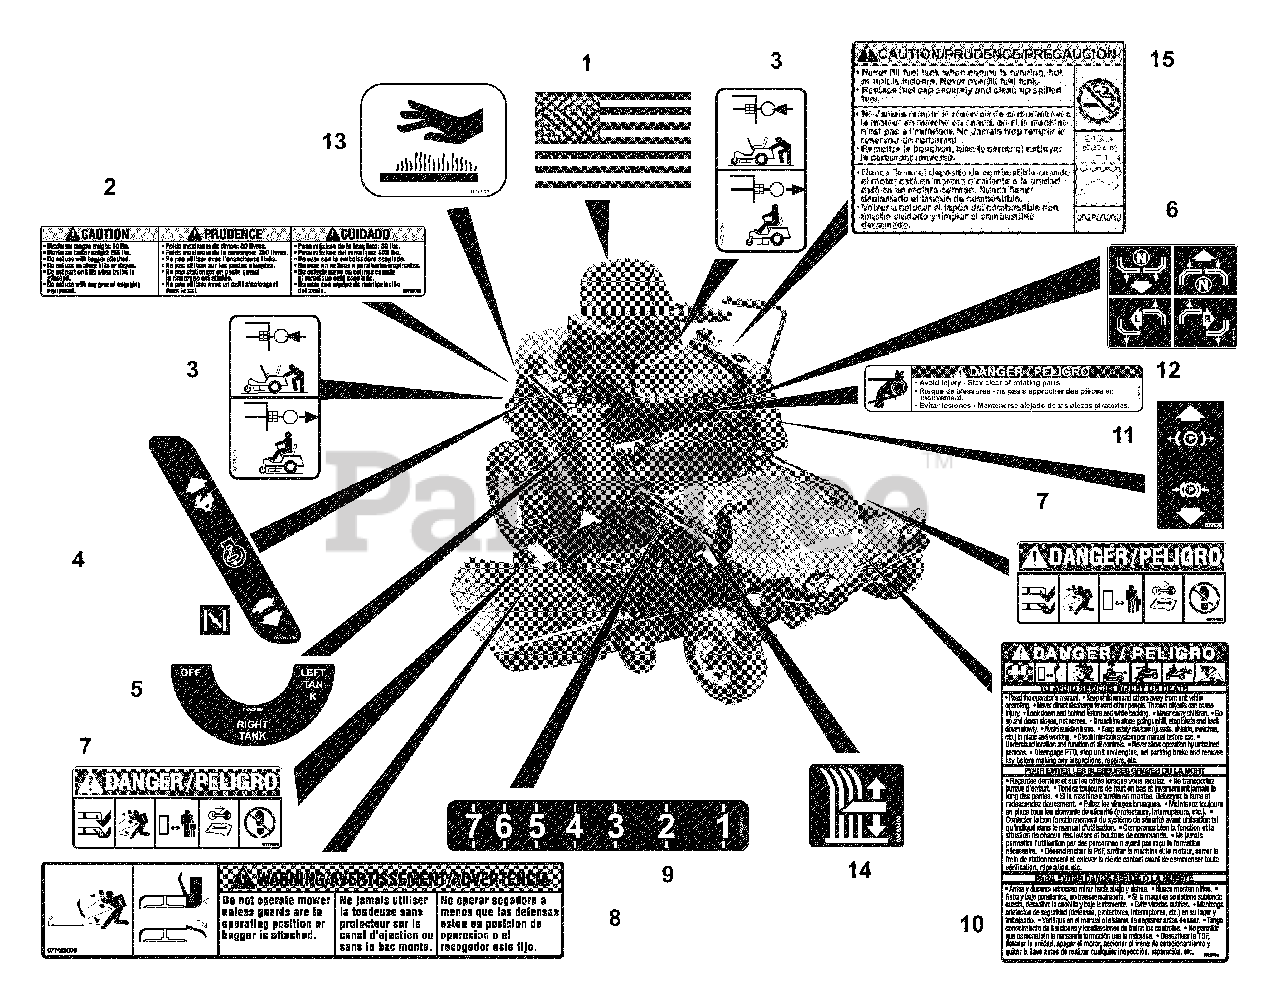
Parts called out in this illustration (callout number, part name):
1	DECAL, AMERICAN FLAG
2	DECAL, TRAILER HITCH
3	DECAL, TRANSMISSION DISCONNECT
4	DECAL, SPEED CONTROL
5	DECAL, FUEL VALVE
6	DECAL, INSTRUCTIONAL-STEERING
7	DECAL, MOWER PAN DANGER
8	DECAL, WARNING
9	DECAL CUT HEIGHT
10	DECAL, DANGER BILINGUAL
11	DECAL, PARKING BRAKE LEVER
12	DECAL- DANGER
13	DECAL, HOT SURFACE
14	DECAL-CUT HEIGHT
15	DECAL,FUEL WARNING
